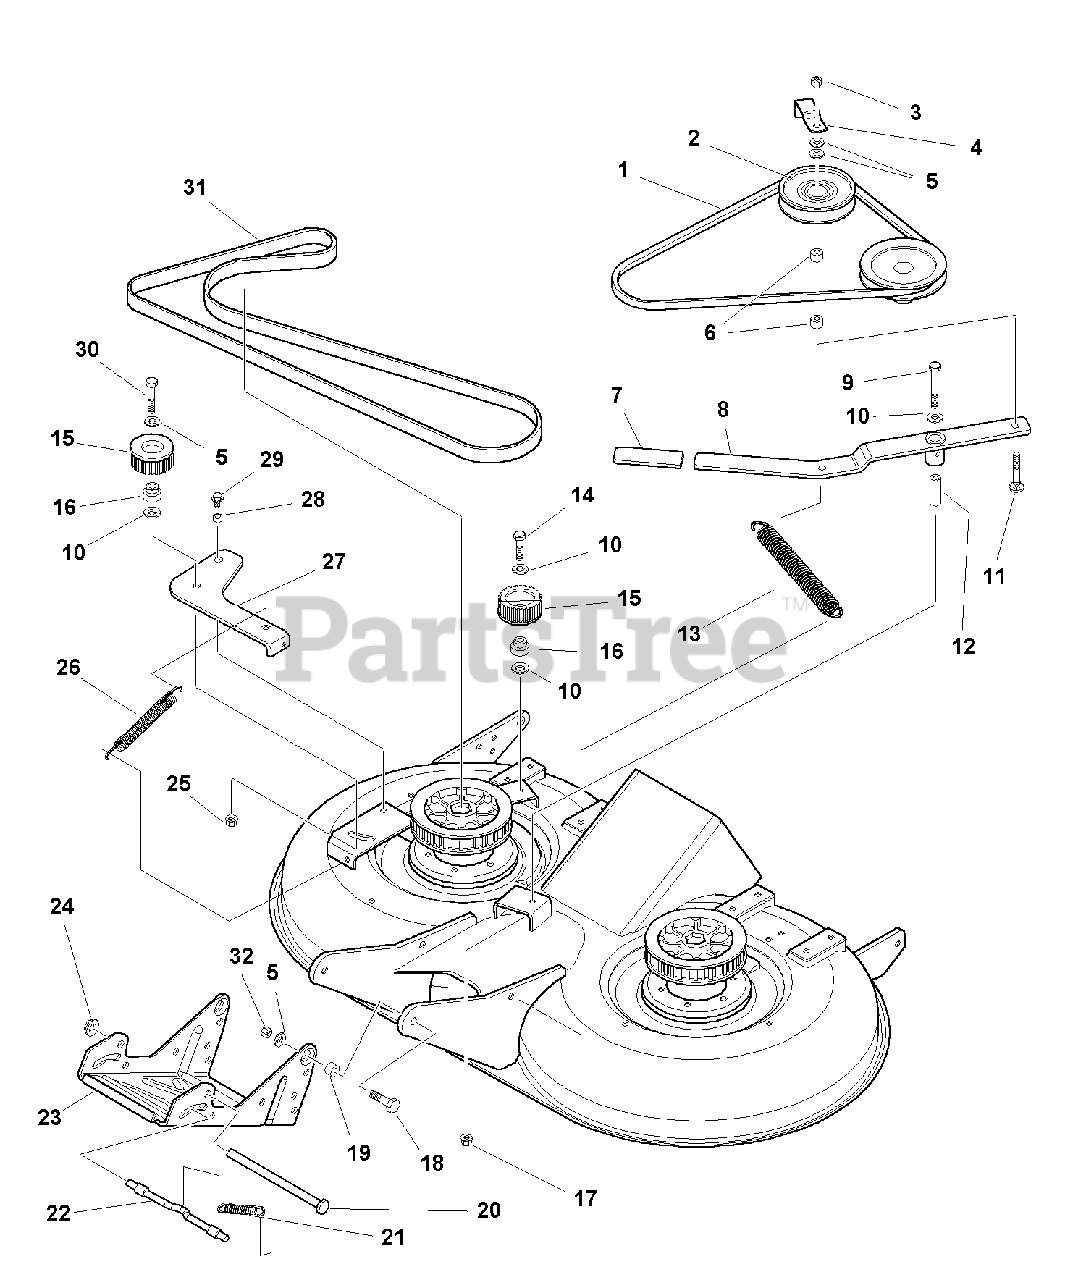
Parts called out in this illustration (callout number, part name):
1	V-BELT, Mower Drive, PTO
3	NUT, Hex Lock ESNA Light, 3/8-16
5	WASHER, 3/8
7	GRIP, Black Vinyl
8	ARM ASSEMBLY, Idler w/Bushings & Lube
9	CAPSCREW, Hex Head, 3/8-16 x 2-3/4 G8
10	WASHER, 3/8
11	CARRIAGE BOLT, 3/8-16 x 2-1/2
13	SPRING, Extension
14	CAPSCREW, Hex Head, 3/8-16 x 1-3/4
15	PULLEY, Idler 22 Teeth
17	NUT, Hex Flange Whizlock, 3/8-16
18	CAPSCREW, Hex Head, 3/8-16 x 1-1/2
20	ROD, Mower Hitch
21	SPRING, Extension
23	HITCH, Mower
24	NUT, Push On
25	WASHER & LOCK NUT ASSEMBLY, 3/8-16
26	SPRING, Extension
27	ARM, Idler
29	CAPSCREW, Hex Washer Head, Taptite, 5/16-18 x 1/2
30	CAPSCREW, Hex Head, 3/8-16 x 2
31	BELT, Timing, Arbor Drive
32	NUT, Hex Lock ESNA Heavy, 3/8-16
